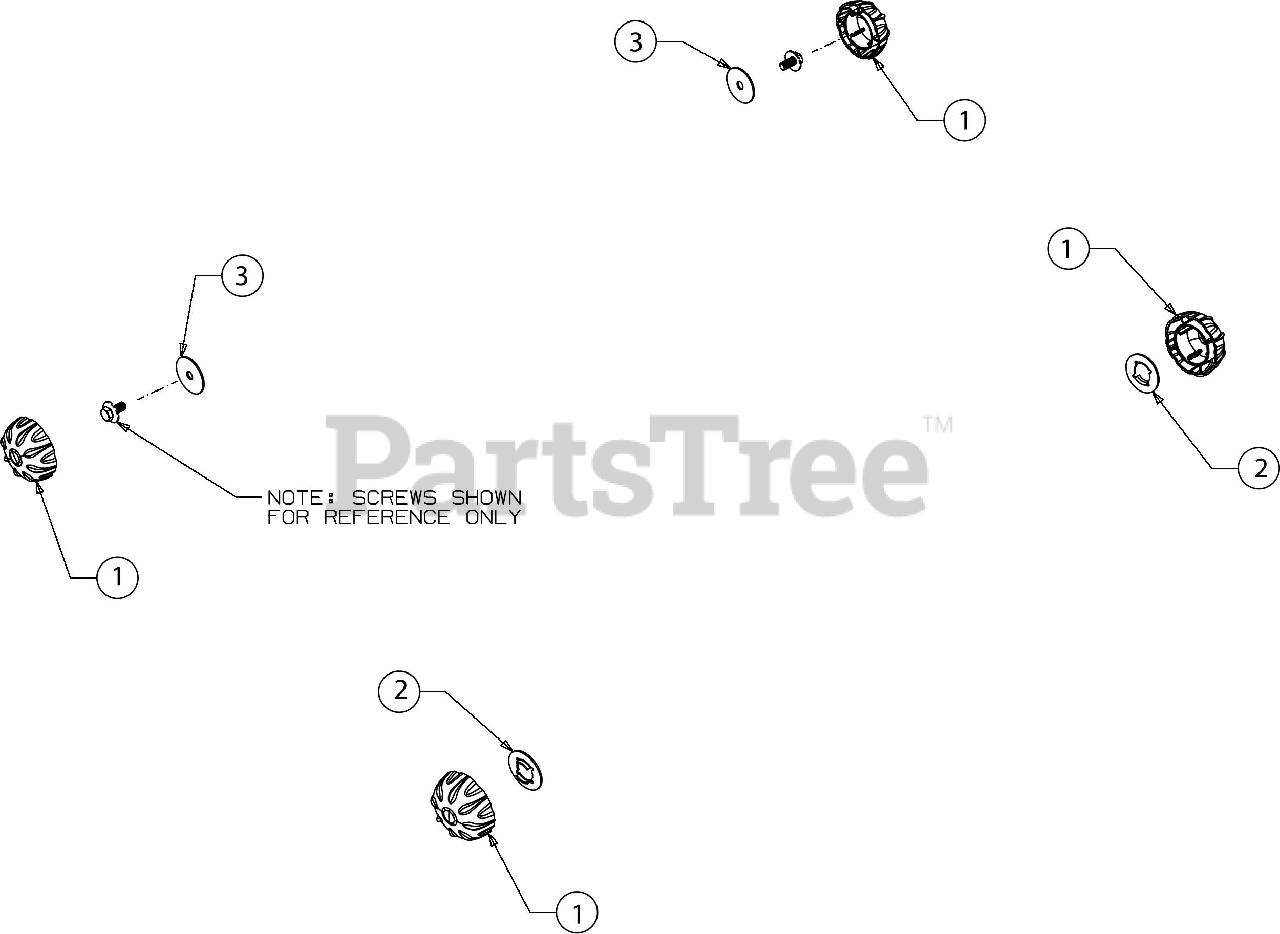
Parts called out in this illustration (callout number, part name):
1	HUB CAP
2	FLAT WASHER .781 ID x1.590 OD
3	FLAT WASHER .350X1.59X.062
